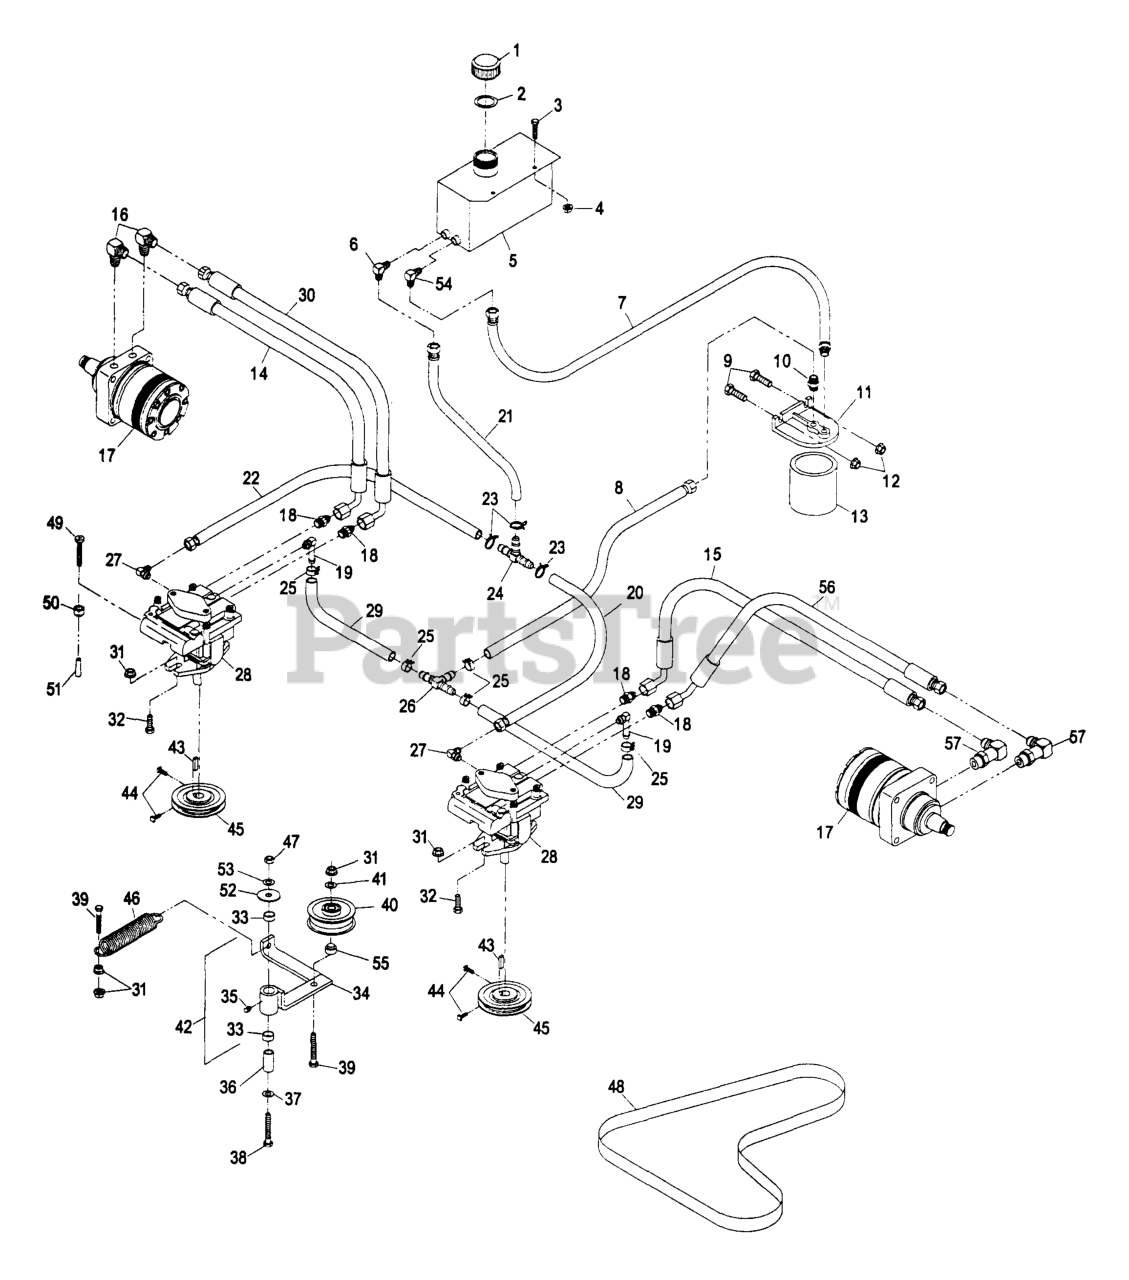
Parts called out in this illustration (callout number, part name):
2	GASKET-CAP, TANK
6	FITTING-ELBOW
10	FITTING-STRAIGHT
14	HOSE-FRONT
15	HOSE,HYDRAULIC
16	FITTING-HYD, 90 DEG
17	MOTOR-WHEEL
18	FITTING-STRAIGHT
19	FITTING
20	HOSE ASM
22	HOSE ASM
23	CLAMP-HOSE
24	FITTING-TEE, HOSE
25	CLAMP-HOSE
26	FITTING-TEE, HOSE
27	FITTING-90 DEG
30	HOSE-REAR, RH
33	SLEEVE-BEARING
36	BUSHING
46	SPRING-EXTENSION
51	GRIP-VALVE, DUMP
54	FITTING-ELBOW
55	BUSHING-IDLER
56	HOSE,HYDRAULIC
57	FITTING-90 DEG
